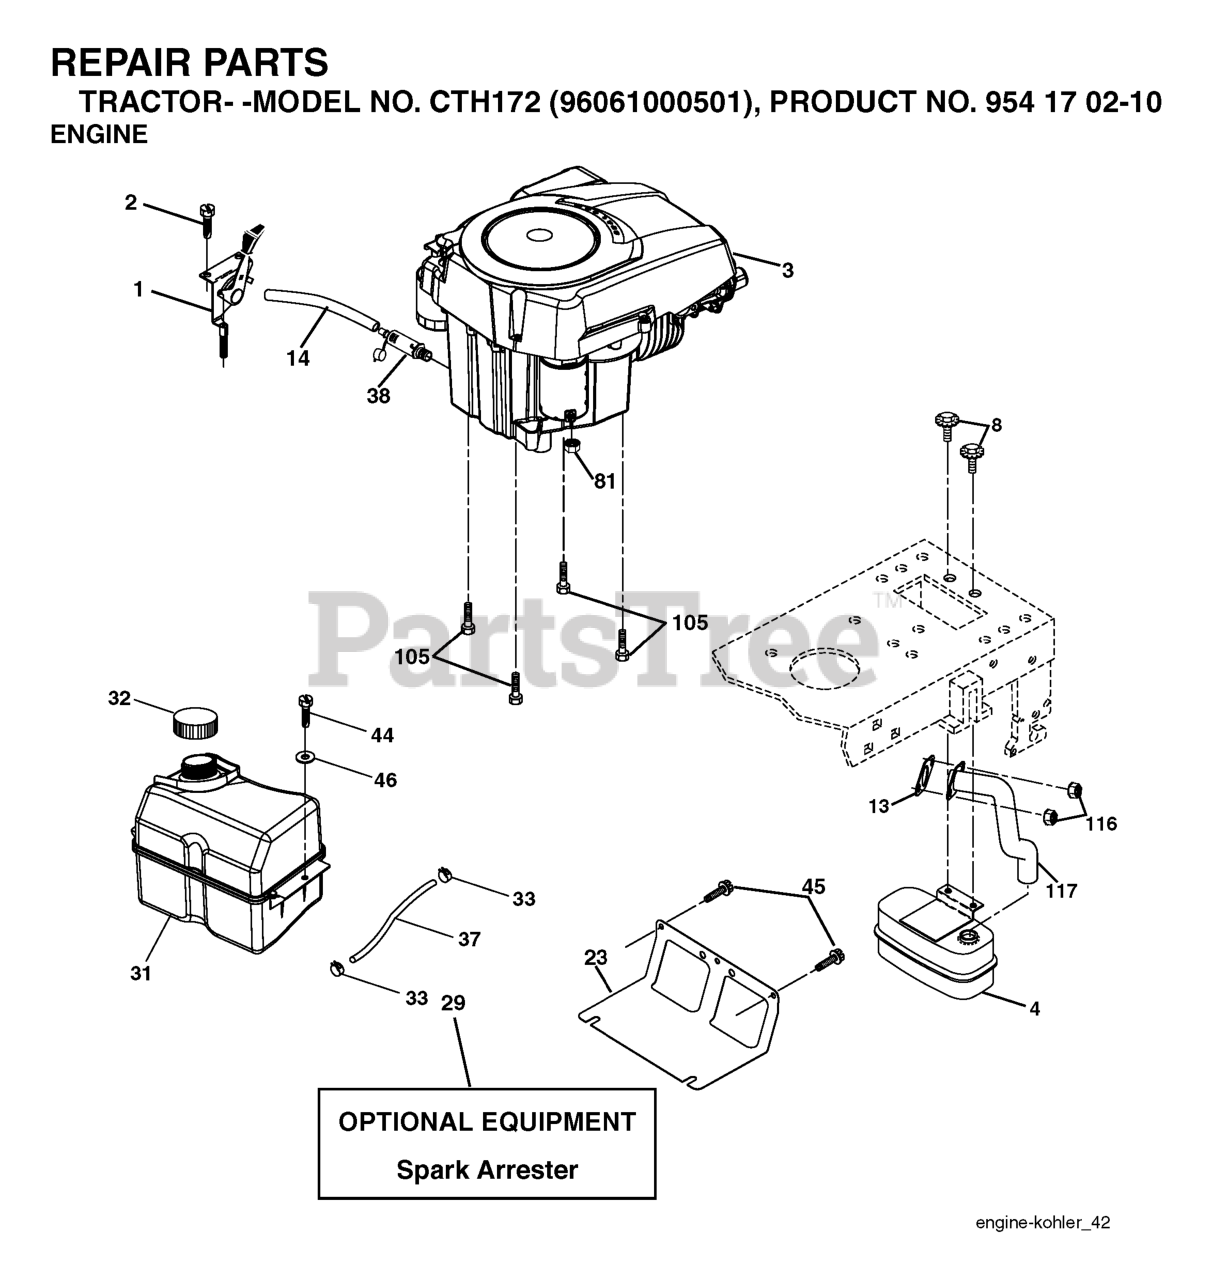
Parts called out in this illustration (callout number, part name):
1	CONTROL.THROTTLE.LT/YT
2	SCREW
4	MUFFLER.SINGLE.CYL.KOHL/B&S
8	BOLT.5/16-18UNCX3/4 W/SEMS.BLK
13	GASKET.EXHAUST.KOHLER
14	TUBE, DRAIN OIL ASM.
23	SHIELD.BROWNING.DBR.GUARD
29	KIT.SPARK ARRESTOR 794945 B&S
31	TANK FUEL
32	FUEL CAP
33	HOSE CLAMP
37	LINE.FUEL.20
38	PLUG DRAIN OIL EASY
44	SCREW HEXWSHR 1/4-20X3/4
45	SCREW, 3/8-16X3/4
81	NUT
105	SCREW 3/8-16X1
116	NUT.HEX.FLANGE.TOPLOCK
117	RP.TUBE.EXHAUST.KOHL.COURAGE
